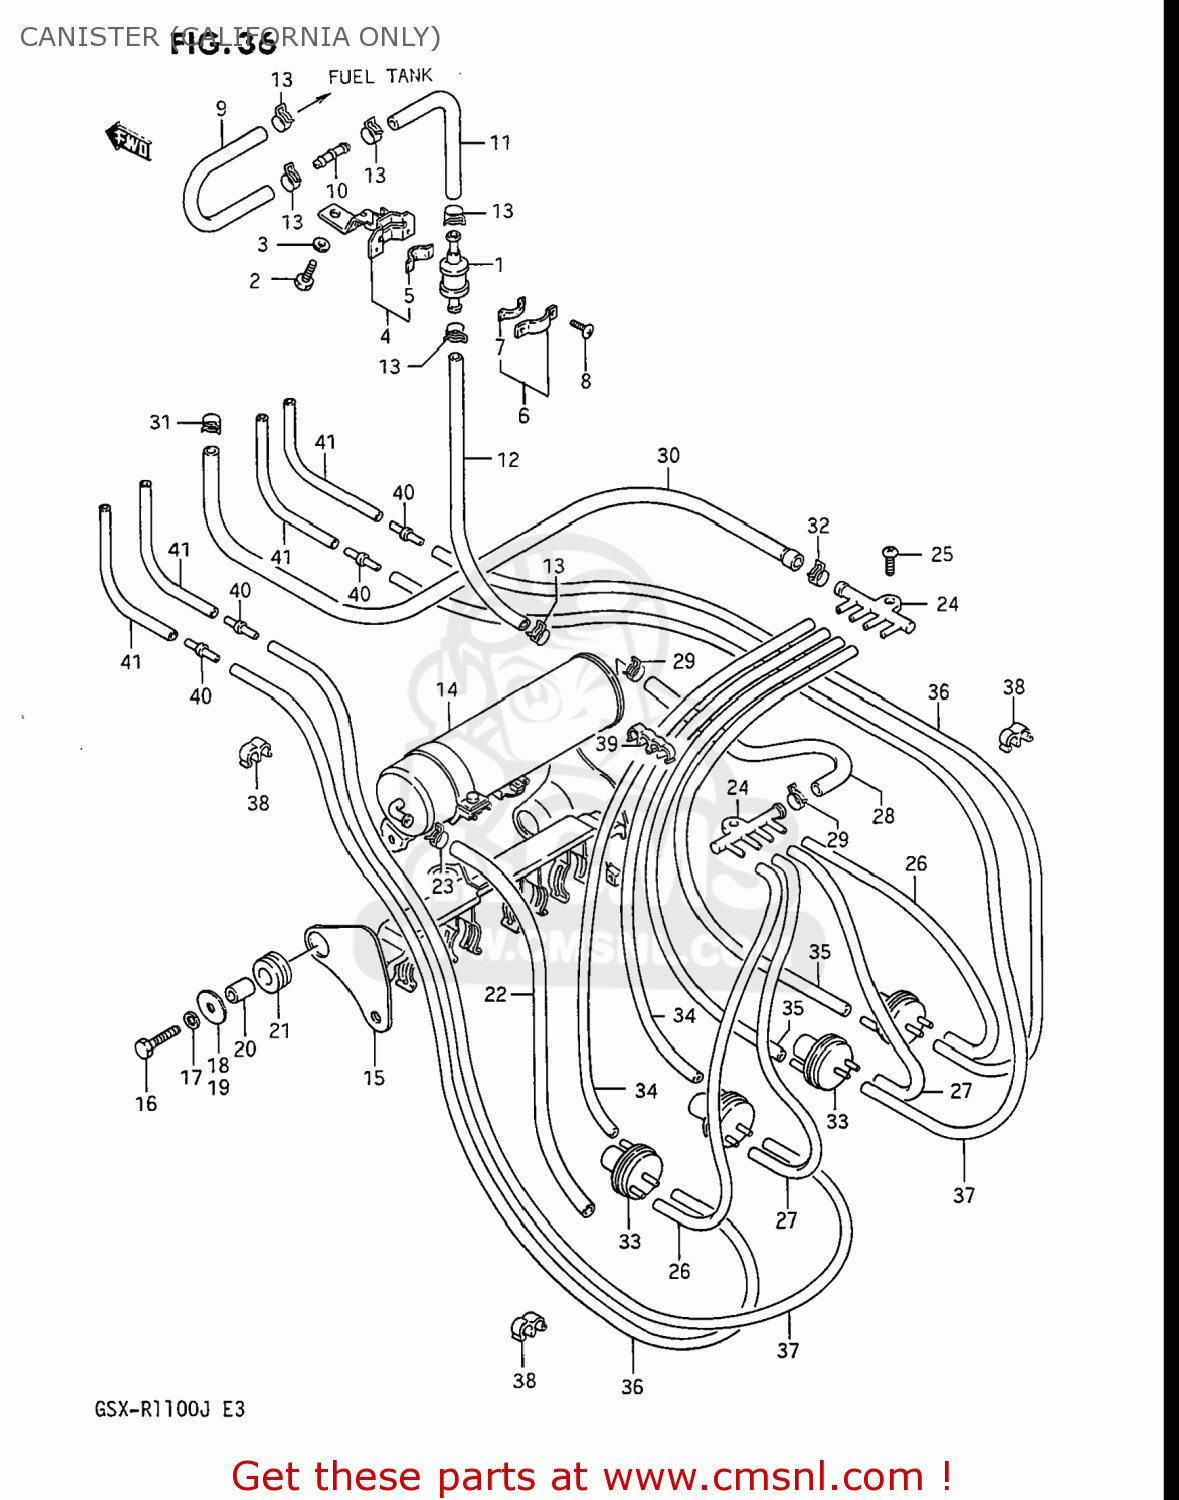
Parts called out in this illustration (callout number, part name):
1	VALVE,FUEL TANK BREATHER
2	BOLT
3	WASHER,LOCK
5	CUSHION
6	PLATE,FUEL TANK BREATHER NO.2
7	CUSHION
8	SCREW
9	HOSE
10	UNION
11	HOSE
12	HOSE
13	(CA) CLIP
14	(CA) CANISTER ASSEMBLY,CHARCOAL
15	BRACKET,CANISTER
16	BOLT
17	WASHER
18	WASHER
19	WASHER (6.5X22X1.6)
20	SPACER(6.5X11.5X12)
21	CUSHION
22	HOSE
23	CLAMP
24	SEPARATOR
25	SCREW
26	HOSE
27	HOSE
28	HOSE
29	CLAMP
30	HOSE
31	(CA) CLIP
32	CLAMP
33	(CA) VALVE,VACUUM CONT
34	HOSE
35	HOSE
36	HOSE
37	HOSE
38	CLAMP
39	CLIP
40	2 WAY
41	HOSE
